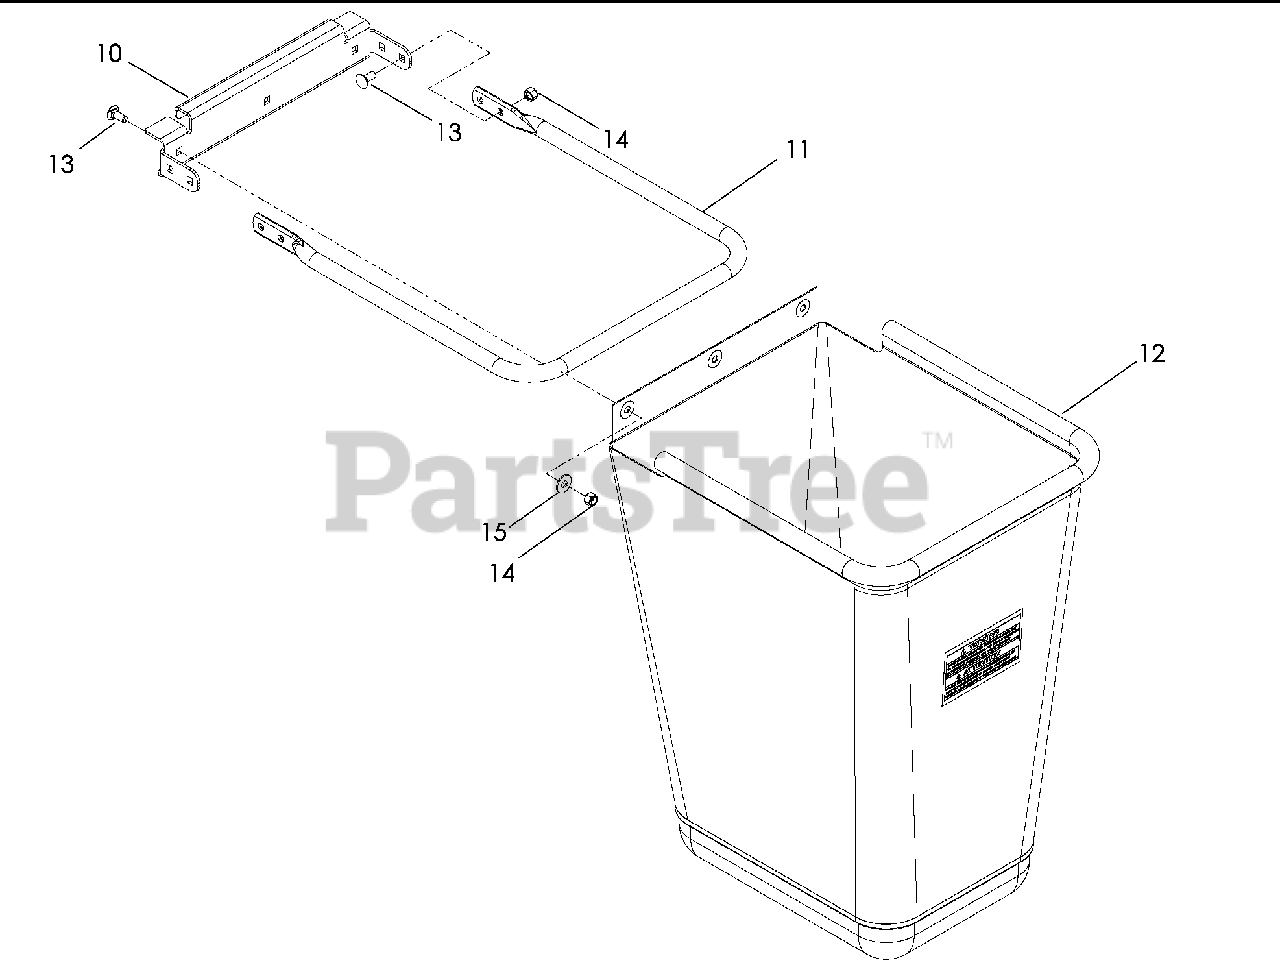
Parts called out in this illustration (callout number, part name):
1	HANGER, BAG
2	TUBE, BAG FRAME
3	BAG, LARGE, MODEL
4	RHSNB 5/16-18 x ¾
5	NUT 5/16-18 NYLOC
6	WASHER 5/16
